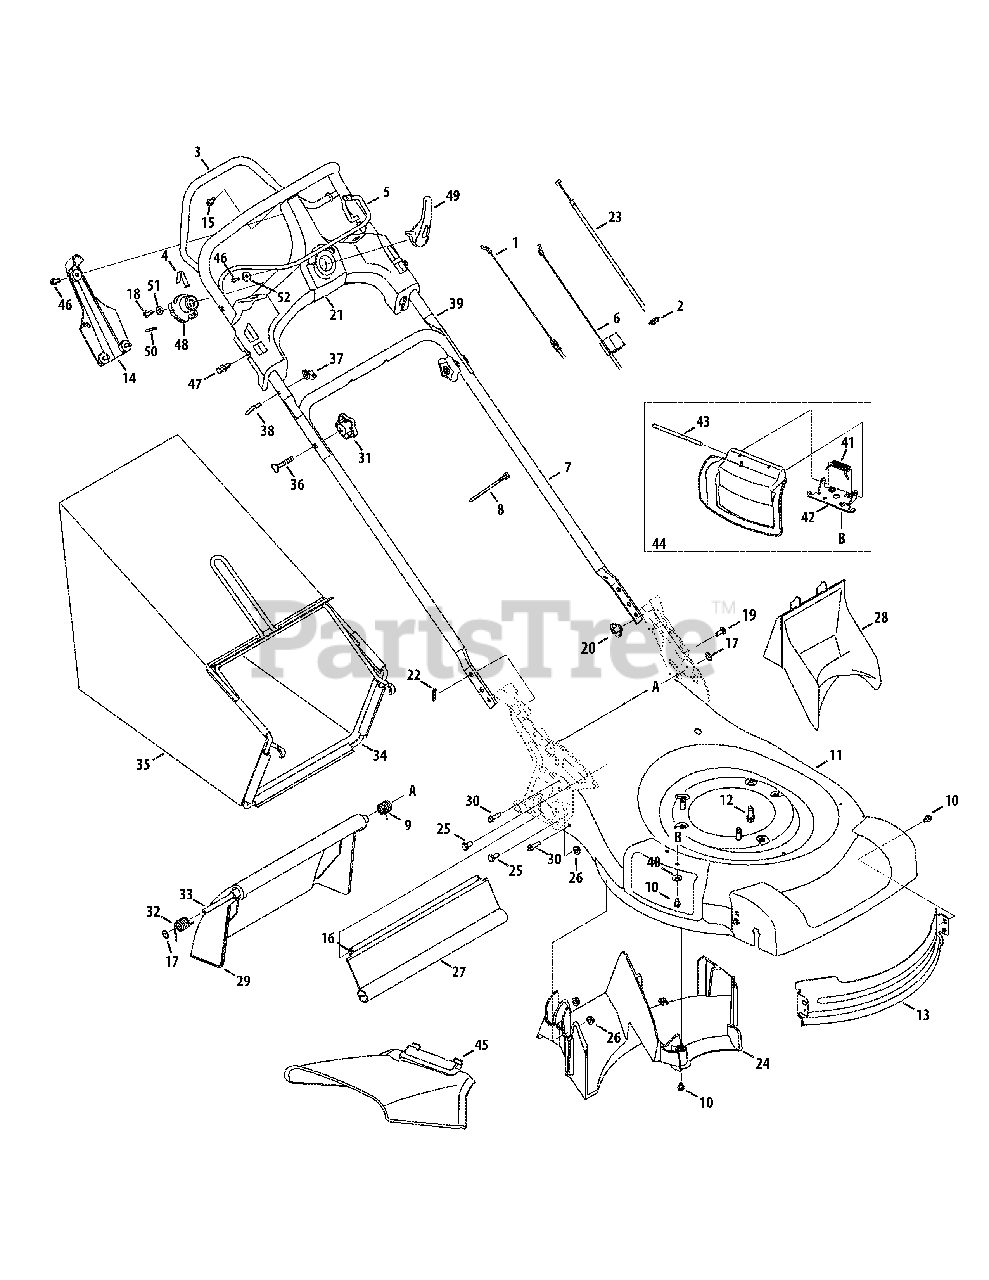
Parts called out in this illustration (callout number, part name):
1	Drive Cable
2	Rubber Grommet
3	Drive Control
4	Shift Spring
5	Blade Control
6	Control Cable
8	Cable Tie
9	Torsion Spring, LH
10	TT Screw, 1/4-20 x .500
12	TT Screw, 3/8-16 x 1.00
13	Front Deck Bae
14	Variable Speed Cont. Panel Cover
15	Screw, AB, 1/4-14 x .625
16	Screw, #10-16 x .500
17	Nut, Speed
18	Screw, 1/4-15 x .750
19	Carriage Bolt, 1/4-20
20	Wing Nut
21	Variable Speed Control Panel
22	Cotter Pin
23	Variable Speed Cable
25	Screw, 5/16-18 x .625
26	Flange Lock Nut, 5/16-18
27	Trail shield
28	Mulch Plug
29	Rear Door
30	Screw, 1/4-15 x 1.00
31	Star Knob
32	Torsion Spring, RH
34	Grass Catcher Frame
35	Grass Catcher
36	Carriage Bolt, 5/16-18 x 2.00
39	Upper Handle
40	Bell Washer, .265 x .75 x .062
41	Torsion Spring
42	Chute Deflector Adapter
43	Hinge Pin
44	Mulch Plug Assembly
45	Side Discharge Chute
46	Screw, #12-16 x .75
47	Rivet, Plastic
48	4 Speed Actuator
49	Speed Selector Level
51	Washer, Flat, .344 x .688 x .065
52	Washer, Flat, .250 x .750 x .119
